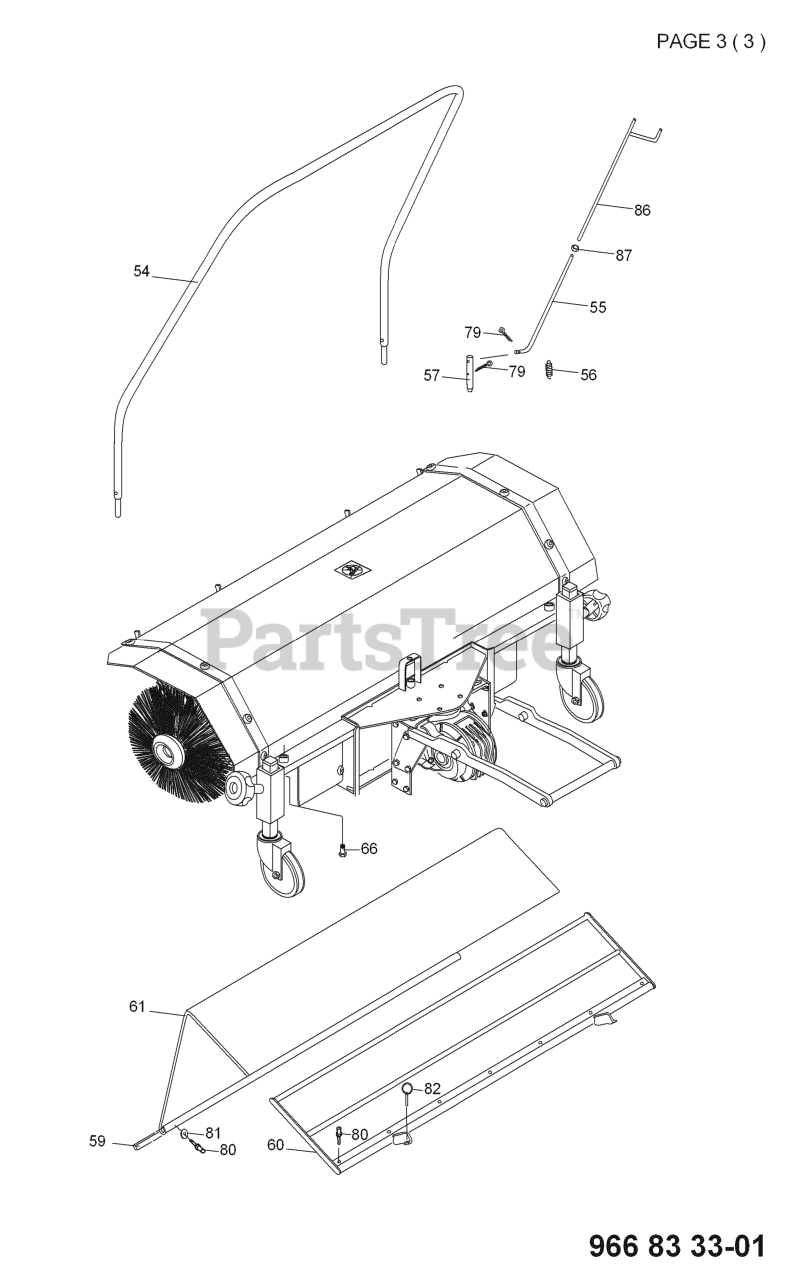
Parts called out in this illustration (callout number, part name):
57	PIN RETAINING SCREW
61	PROTECTION
79	PIN RETAINING SCREW
